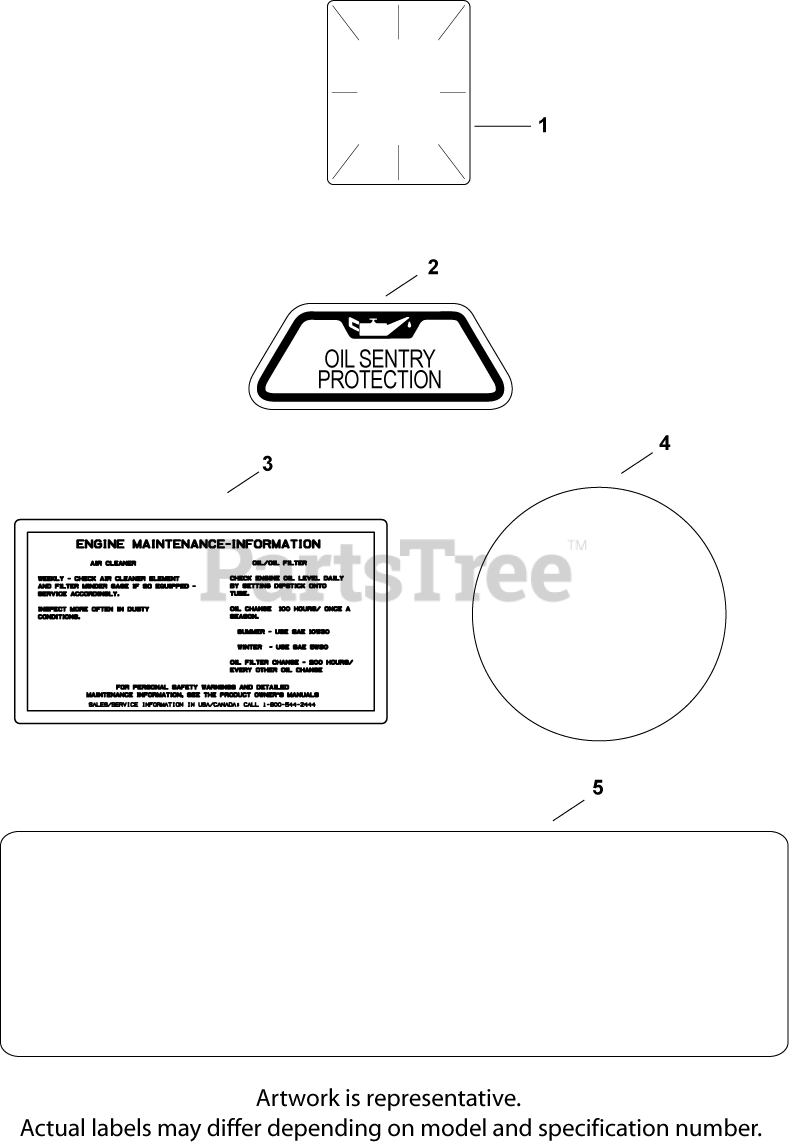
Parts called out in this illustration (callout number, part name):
1	DECAL, CLEAR LAMINATE USE 25 113 70-S
2	DECAL, OIL SENTRY - (#DSC)
3	DECAL, AIR CLEANER - (#DSC)
4	LABEL, (ROUND KOHLER GOLD)-USE 24 113 18
5	DECAL, 22 HP
